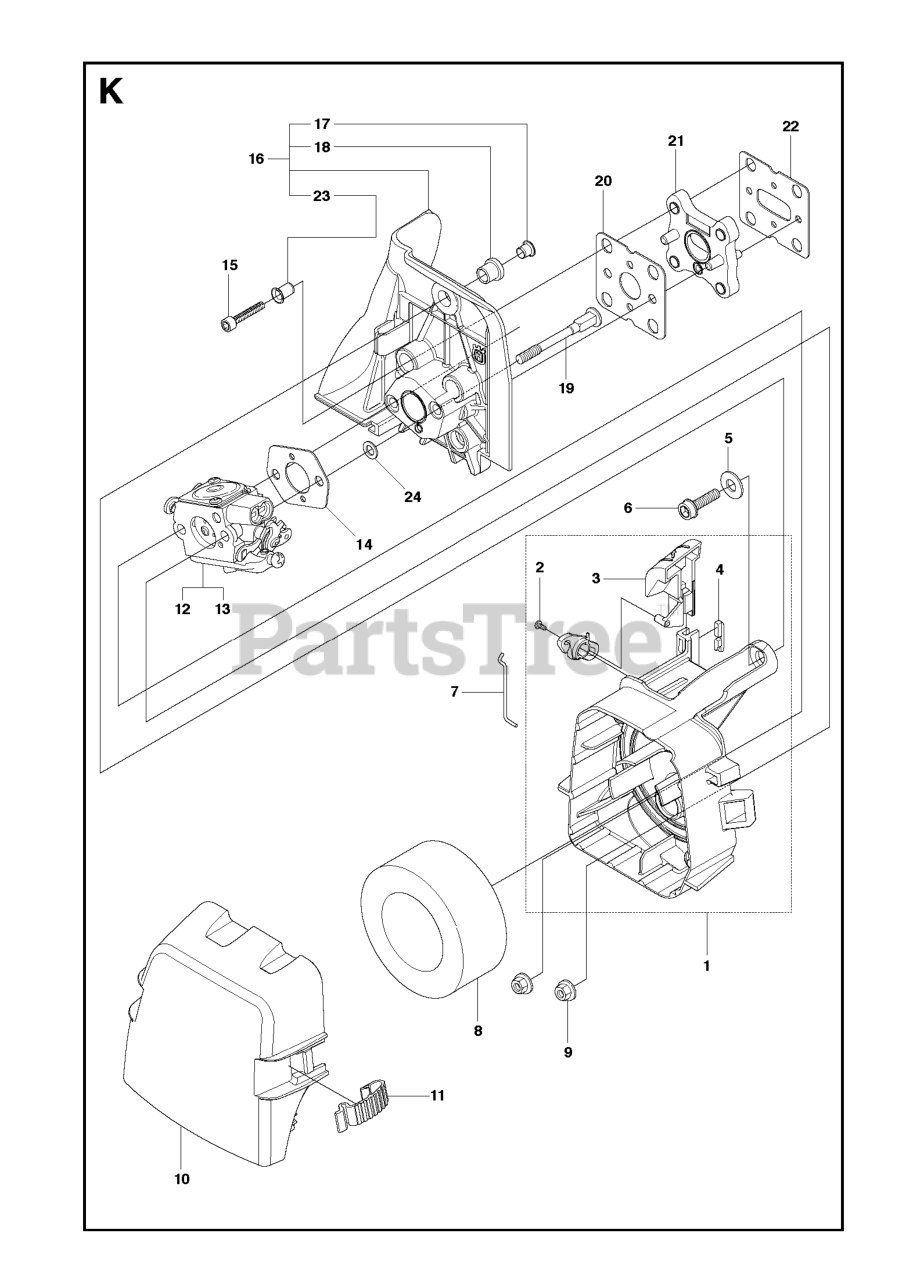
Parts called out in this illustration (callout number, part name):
1	FILTER HOLDER ASSY
3	CHOKE CONTROL
6	SCREW IHSCFM
10	FILTER COVER
12	CARBURETTOR C1Q-EL38
13	CARBURETTOR C1Q-EL39A
15	SCREW
16	INSULATION WALL ASSEMBLY
20	GASKET INTAKE
22	GASKET INTAKE
24	WASHER
